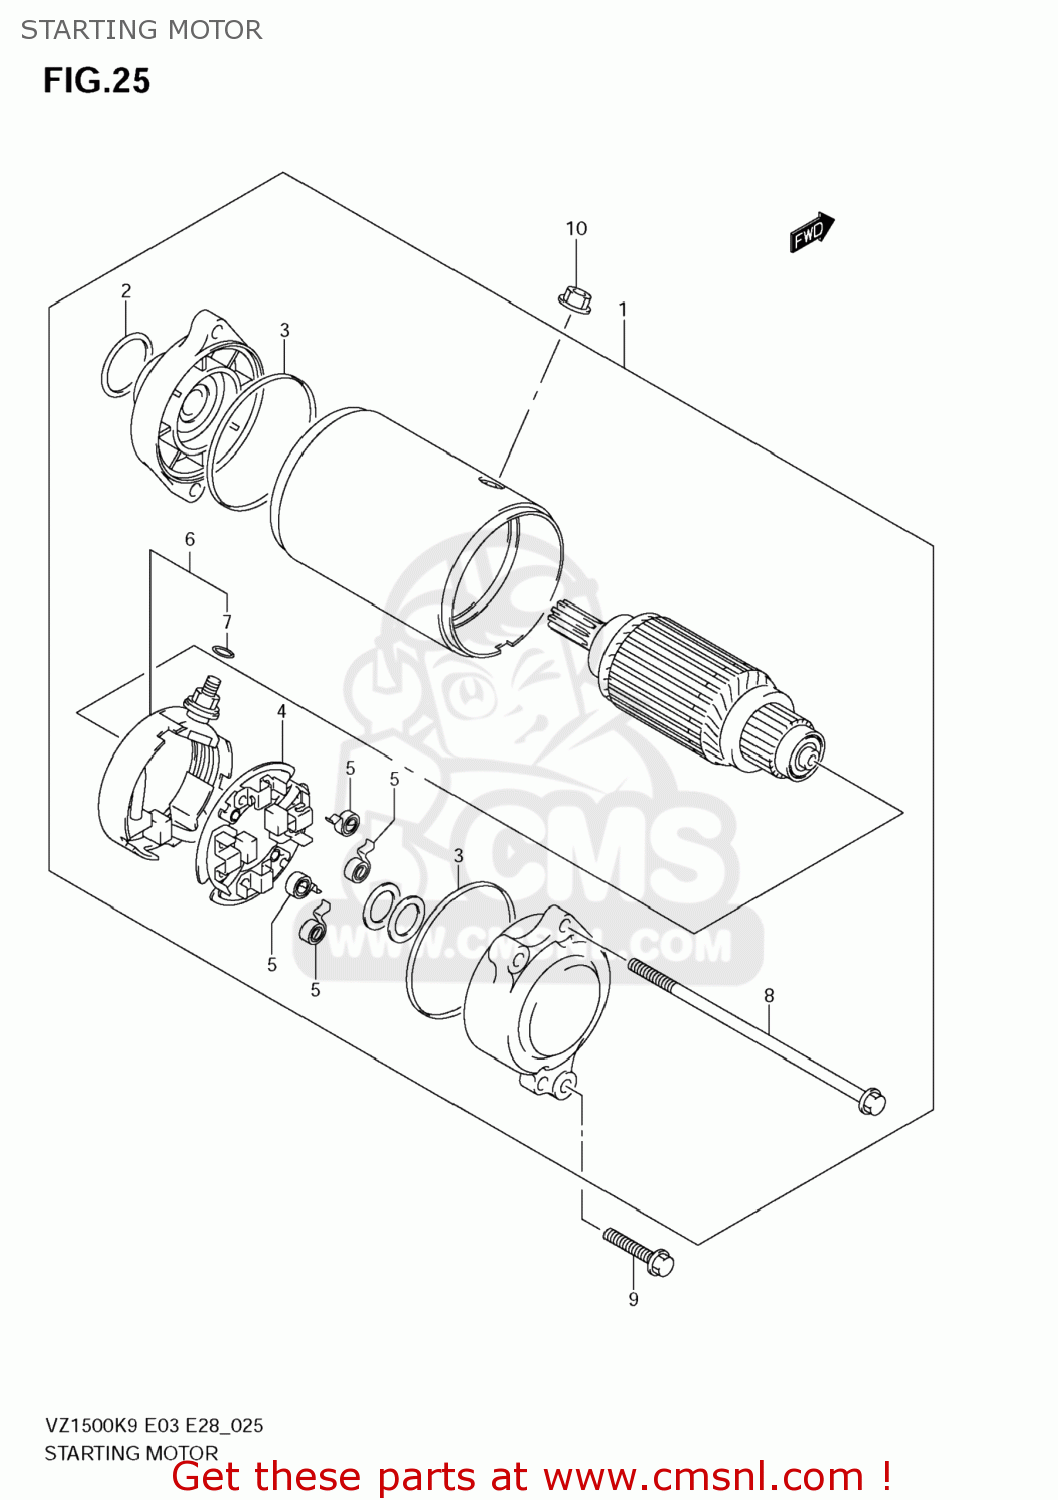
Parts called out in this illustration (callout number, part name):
1	MOTOR ASSY,STARTING
2	O RING(D:3.1,ID:24.4)
3	O RING
4	HOLDER SET,BRUSH
5	SPRING,BRUSH
6	TERMINAL SET,BRUSH
7	O RING
8	BOLT
9	BOLT(6X25)
10	NUT
